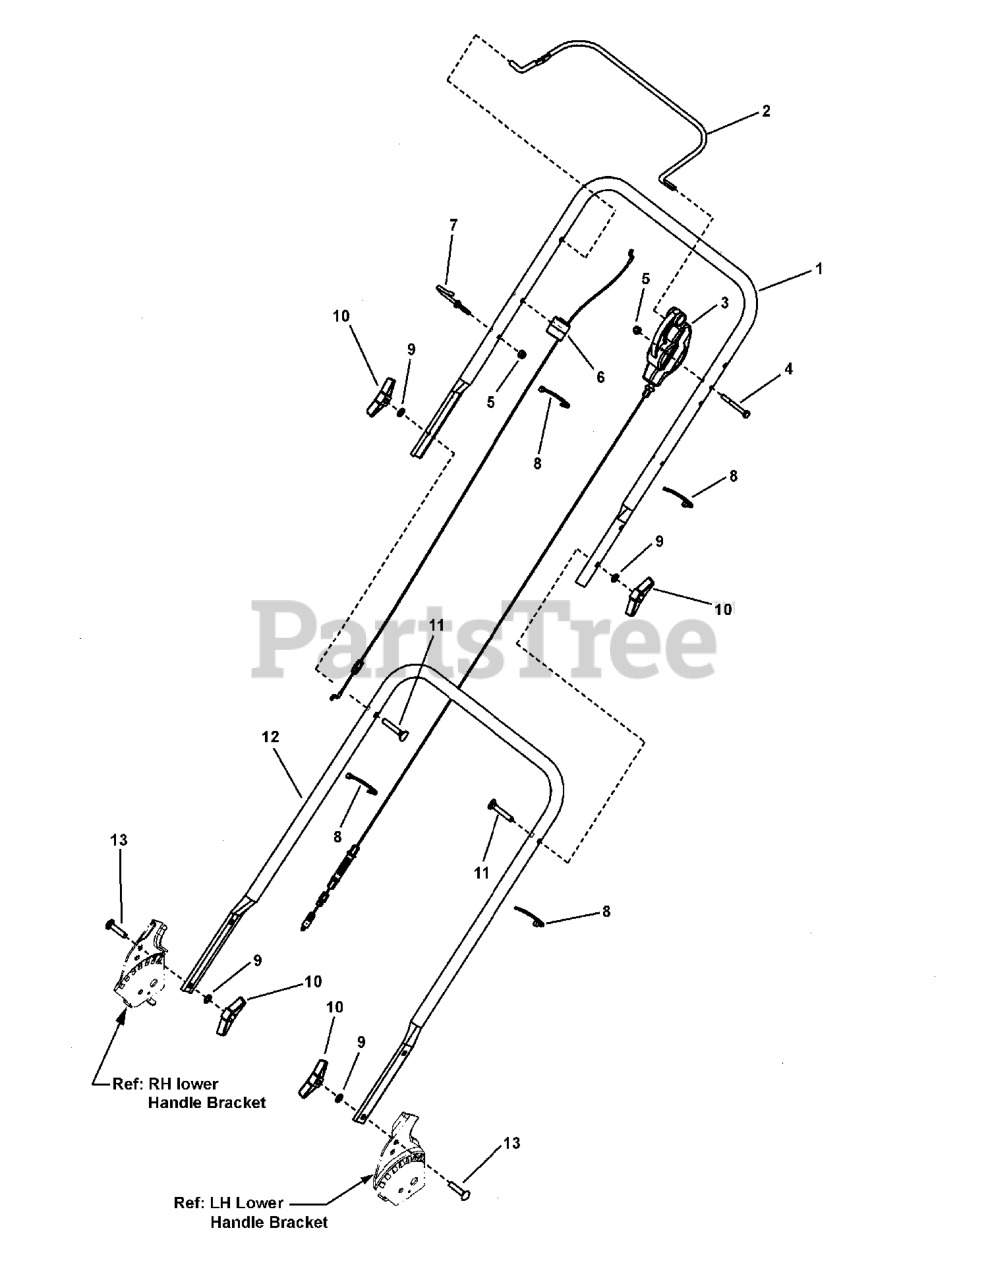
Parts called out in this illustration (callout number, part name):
1	UPPER HANDLE, Murray, Propelled
2	BAIL, OPC Propelled
3	CONTROL, Drive, Single Speed
4	SCREW, 1/4-20 x 2-1/4" Hex Head Cap, GR 5
5	NUT, 1/4-20 Nyloc
6	CABLE, Bail, 22" Brute WBM
7	ROPE GUIDE, (1/4-20 thread)
8	WIRE TIE,11 Inch Std Black Nylon
9	WASHER, 5/16" Internal Tooth lock
10	KNOB, 5/16-18 Wing Nut
11	BOLT, 5/16-18 x 2" Curved Head Square Neck, GR 2
12	HANDLE, Lower Murray, MY 09
13	BOLT, 5/16-18 x 1-1/2" Round Head Short Square Neck Carriage, GR 5
